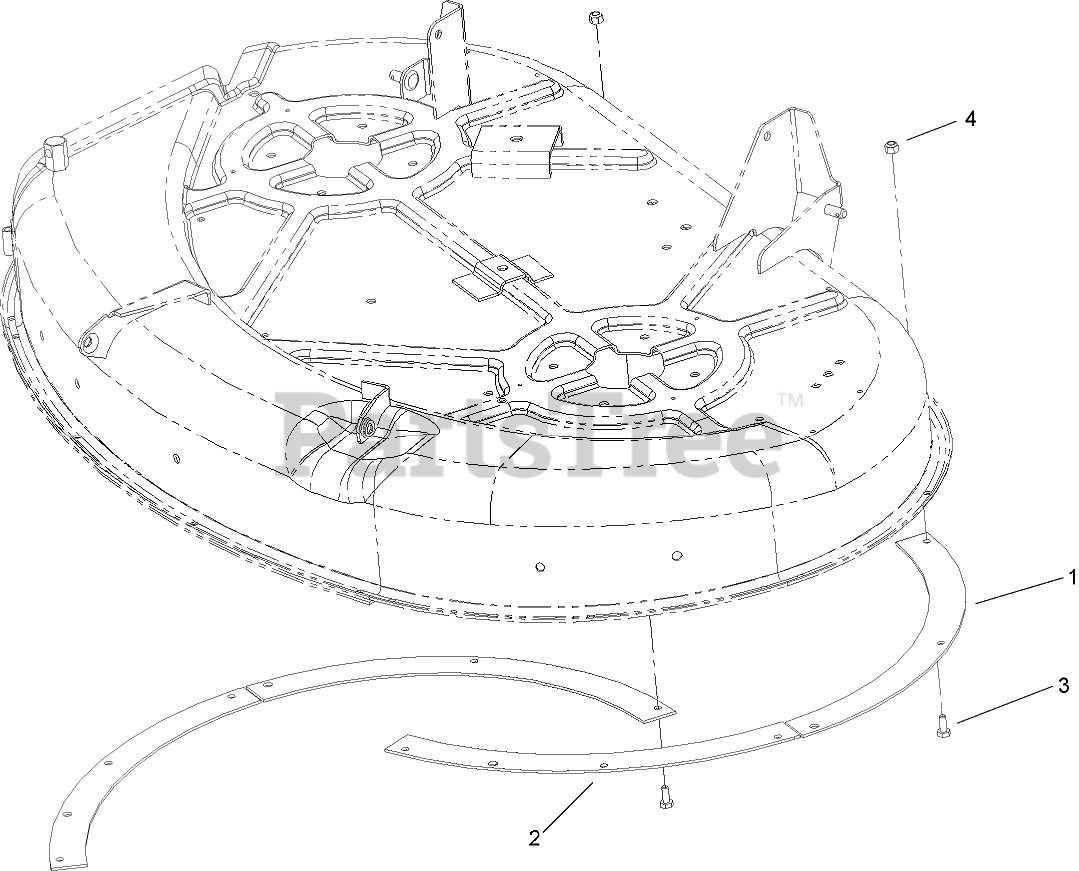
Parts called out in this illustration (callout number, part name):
1	RING-BLOW OUT, SIDE
2	RING-BLOW OUT, SIDE
3	SCREW-HH
4	NUT-LOCK, NI
